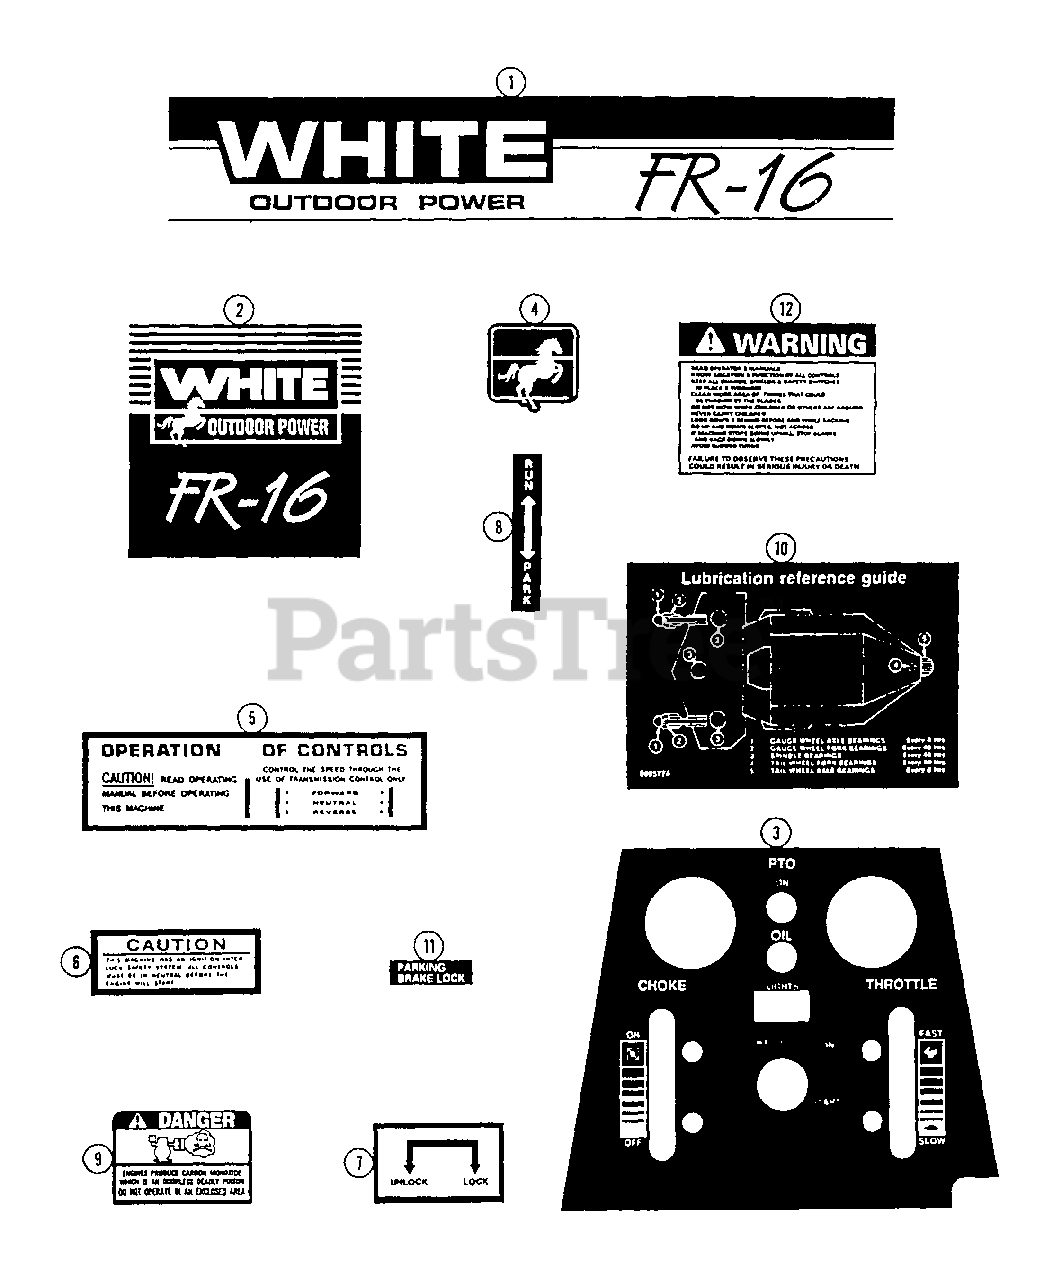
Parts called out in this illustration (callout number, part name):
1	DECAL - L.H.
1	DECAL - R.H.
2	DECAL - front
3	DECAL - instrument panel
4	MEDALLION - "Stallion logo"
5	DECAL - operation
6	DECAL - caution interlock
7	DECAL - unlock/lock
8	DECAL - run/park
9	DECAL - danger carbon monoxide
10	DECAL - lubrication
11	DECAL - brake lock
12	DECAL - warning
